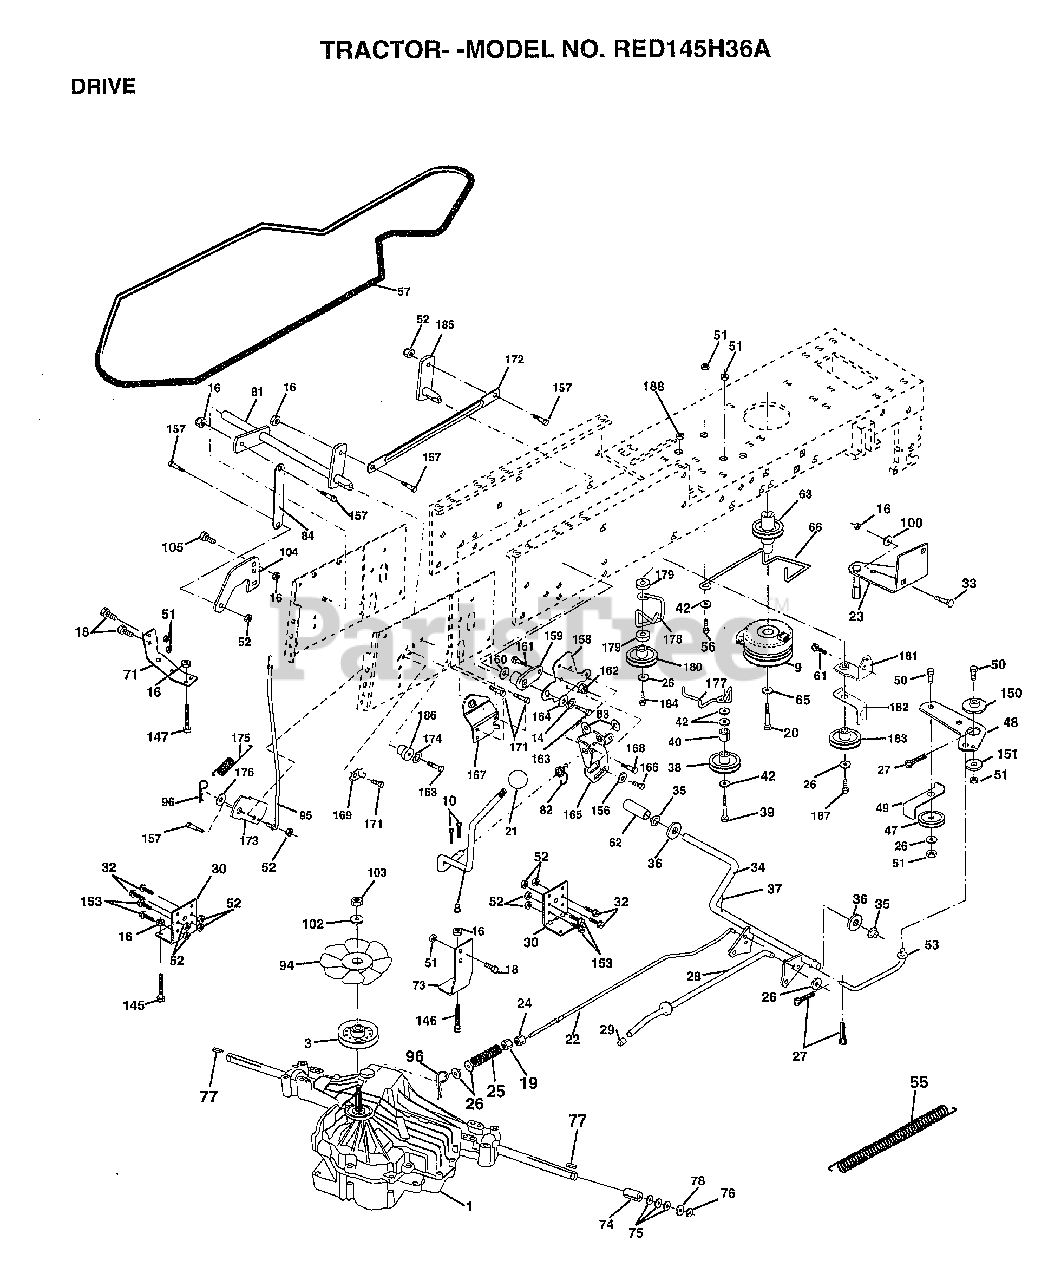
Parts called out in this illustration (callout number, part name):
3	PULLEY.TRANSAXLE
8	ROD.SHIFT.FENDER.ADJ.LT.CRD
9	CLUTCH.ELEC.EVX
10	PIN COTTER 1/8
14	LOCKWASHER
16	NUT
18	BOLT
19	NUT
20	BOLT.7/16-20X4.25
21	KNOB T (1/2-HOLE)
22	ROD.BRAKE.CRD
23	BRACKET.CLUT.MTG.
24	NUT
25	SPRING ROD LT
26	WASHER
27	COTTER PIN
28	ROD.BRAKE.PARK.LT
29	PLUNGER CAP T
30	TRANSAXLE MTG BKT
32	BOLT
33	BOLT
34	SHAFT.ASM.PEDAL.FOOT.CRD
35	NYLON BEARING
36	WASHER LT
38	PULLEY.FLAT.IDLER
39	BOLT
40	SPACER T
41	STRAP TORQ LH HYD
42	WASHER
48	BELLCRANK.CLUTCH
49	RETAIN BELT
53	"LINK, CLUTCH T"
55	"SPRING, RETURN LT"
57	"V-BELT.KEV.112"""
61	SCREW
62	PEDAL COVER T
63	PULLEY.CLUTCH.EVX
65	LOCKWASHER
66	KEEPER-BELT
73	"STRAP-TORQUE,RH"
74	SPACER SPLIT
75	WASHER
76	E-RING LT
77	SQUARE KEY
78	WASHER
81	ASM.SHAFT
82	"SPRING,TORSION"
83	WASHER
84	LINK.TRANSAXLE
94	"FAN 7"" HYDRO"
95	CNTRL.ASM.BYPASS.HYDRO
96	RETAINER M
100	WASHER M
102	WASHER BELLEVILLE
104	ARM CONTROL HYDRO
105	SCREW CAP 5/16-18
145	BOLT.HEX.FLGHD
146	BOLT.HEX.FLGHD.
147	BOLT.HEX.FLGHD
150	BUSHING.BELLCRANK.GRD.DR
151	WASHER
156	WASHER.SRRTD.5/16
157	"BOLT,SHOULDER"
158	BRKT.SHIFT.MOUNT
159	HUB.SHIFT
160	WASHER
161	BOLT T
164	WASHER.5/8X.281X10GA
165	BRKT.PIVOT.LEVER
166	SCREW.5/16-18X5/8
167	BRKT.SUPT.SHIFT.CRD
168	BOLT.SHOULDER.5/16-18X.561
169	PLATE.FASTENING
171	SCREW LT
172	LINK.SHAFT.CRD.HYDRO
173	BKRT.HYDRO.BYPASS.CRD
175	SPRING.BYPASS.CRD
176	WASHER
177	KEEPOER.FLAT.IDLER
178	KEEPER.BELT.IDLER
179	WASHER
180	PULLEY.FLAT
181	BRKT.IDLER.GRD.DR.CRD
182	"KEEPER.BELT.2.5"".OD.CRD"
183	PULLEY.V-IDLER
184	SCREW.HXWSH.3/8
185	SHAFT.ASM.SHIFTER.FRT.CRD
186	HUB.TAPERED.ROUND.CRD
187	SCREW
